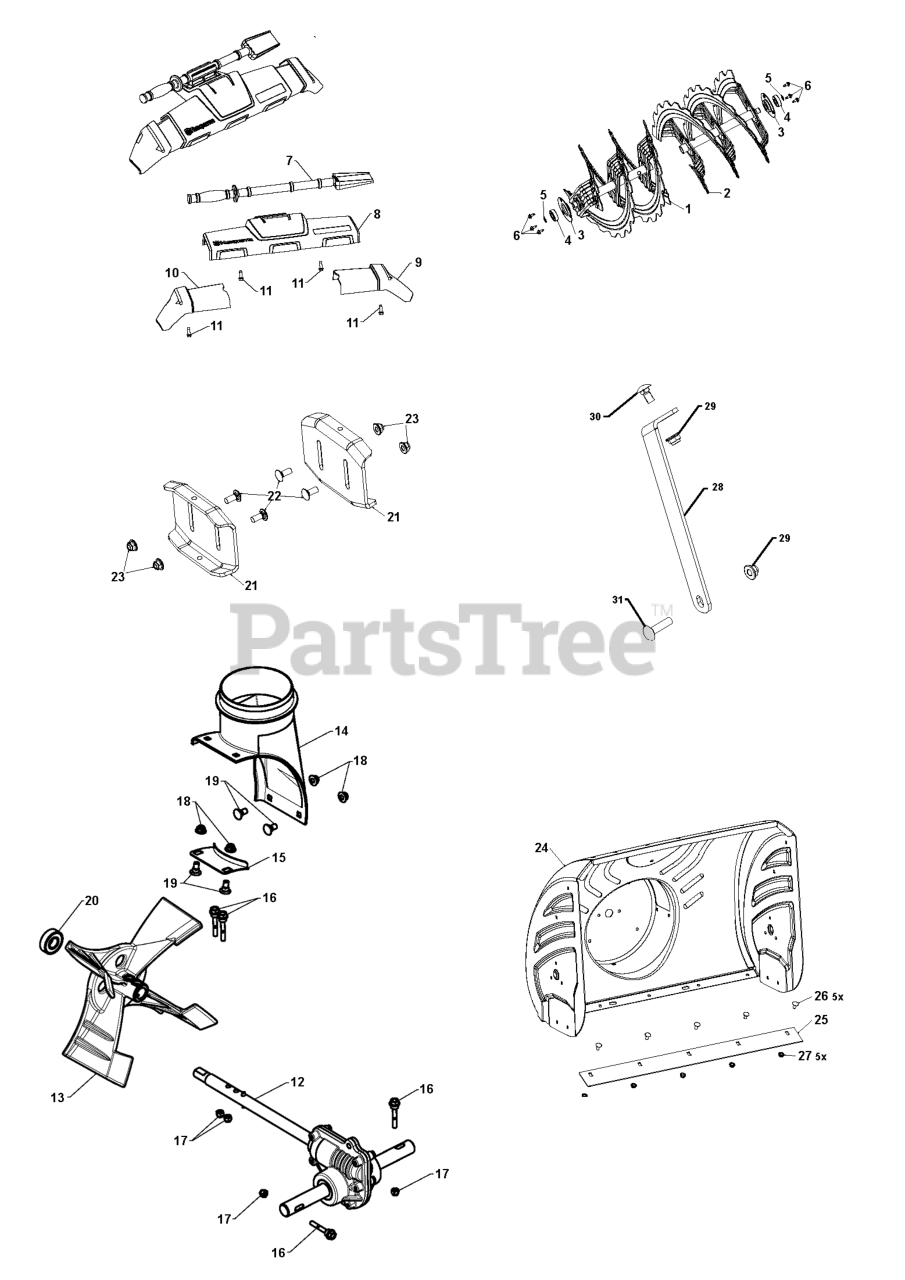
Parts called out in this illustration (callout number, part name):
1	AUGER.RIB.30.RH.LS.GREY
2	AUGER.RIB.30.LH.LS.GREY
3	SUPPORT.BEARING.SINGLE.STAGE.B
4	BEARING.BALL.MANDREL
4	BEARING
5	RETAINING RING LT
6	HEX.WASHER.HEAD 1/4-20 X .65
6	SCREW HEXWSHR 1/4-20X3/4
7	CLEAN OUT TOOL
8	TRIM AUGER FRONT TRIM ASSEMBLY
9	TRIM AUGER.HOUSING.WING.RH MS
10	TRIM AUGER.HOUSING.WING.LH MS
11	SCREW HEXWSHR 1/4-20X3/4
11	SCREW 14-20 X 5/8
12	GEARBOX CAST DD SHAFT
13	IMPELLER CAST.IRON.12IN MS 417
13	Blades
14	CHUTE.DISCHARGE.BASE
16	BOLT SHEAR HX HD 1/4-20 CLEAR
17	NUT HEXAGON 1/4-20 ST ZPB
18	NUT HEX FLG NYLOCK BLK 5_16-1
19	BOLT CARR WAFER BLK 5_16-18 X
21	SKID PLATE
22	BOLT CARR BLK 5_16-18 X .750
23	NUT HEX FLG NYLOCK BLK 5_16-1
24	HOUSING ASSY KIT LS.NF.668 (30
25	PLATE.SHAVE.30.LS.SNOW.BLACK
26	BOLT ROUND HEAD SQUARE NECK BO
27	NUT.FLANGE.5/16
27	GSPW Hardware
28	SUPPORT.GEARBOX.LS.498
29	NUT HEX FLG NYLOCK BLK 5_16-1
30	BOLT CAR BLK 5/16-18 X 5/8
31	BOLT.CARRIAGE.5/16-18
